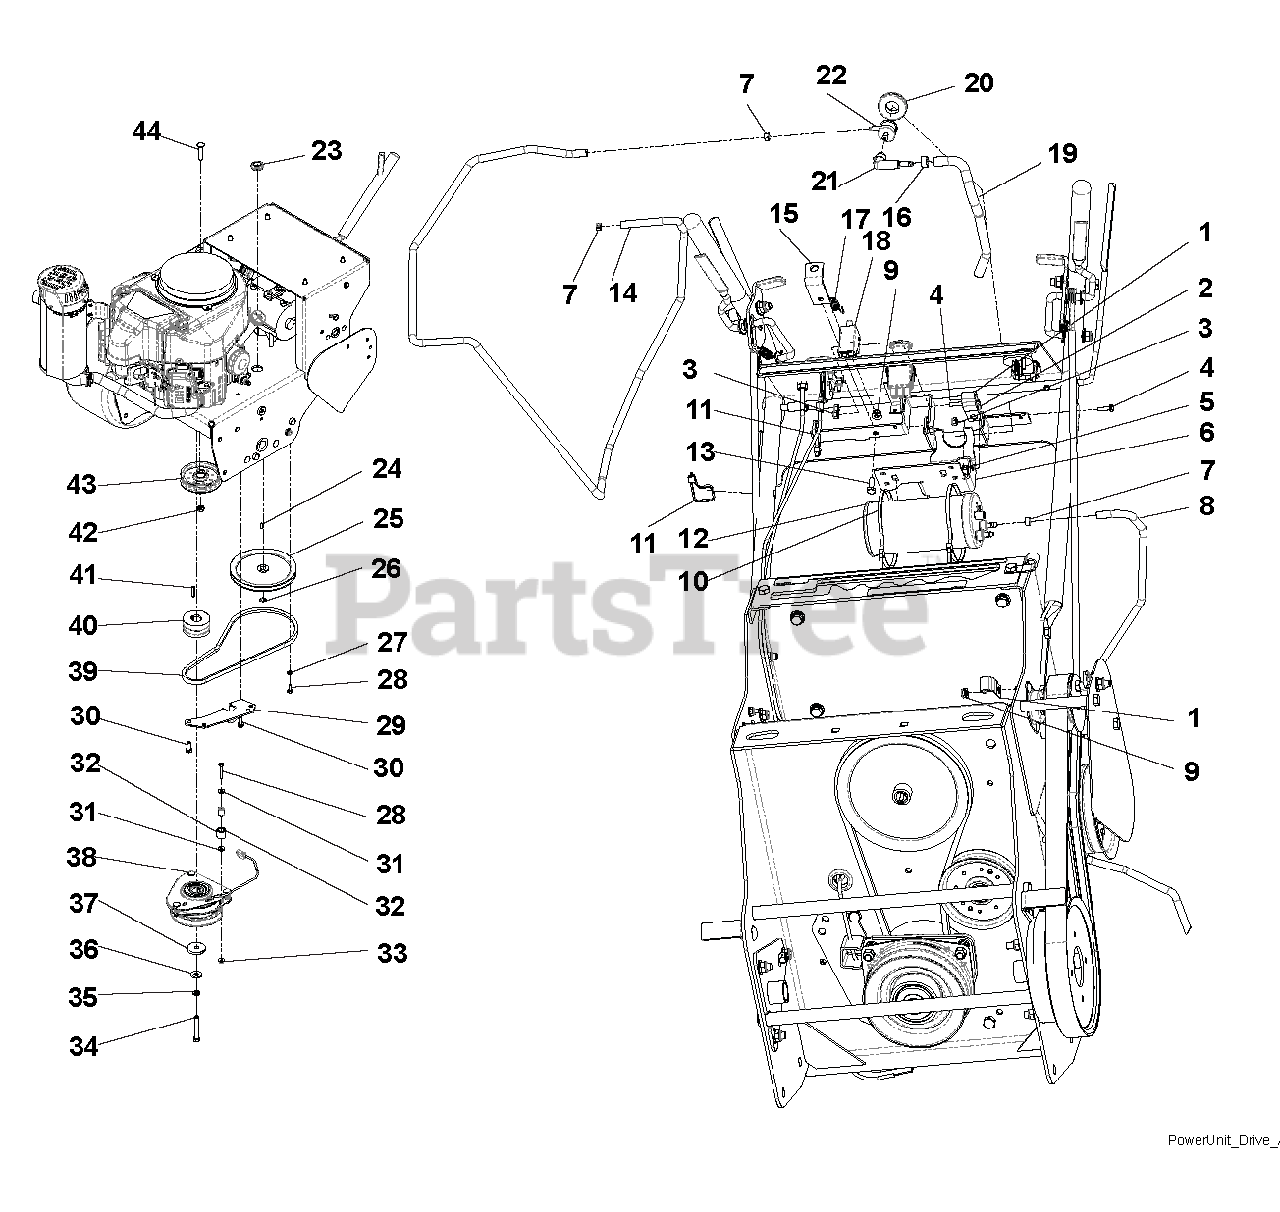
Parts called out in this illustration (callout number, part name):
1	P-CLIP, .500 INSULATED
2	NUT-LK-FLG M8-1.25 YWZC
3	@NUT-LK-NYL 10-24 W/INSRT YWZC
4	@SCR-MCH 10-24X.75 HWH YWZC
5	@BLT-HEX M8 X 1.25X14 YWZC
6	BRACKET, ROV & CC GEAR WALK
7	CLAMP, DBL PINCH 5/16"-7/16"
8	HOSE, PURGE LINE 3/16 GRWLK
9	@NUT-LK-NYL-FLG .25-20 YWZC
10	CABLE TIE, .19 X 14.4
11	CABLE TIE, .15 X 8.50
12	400 CC CARBON CANISTER 3/16 PT
13	@BLT-HEX .25-20X.75 GR5 YWZC
14	HOSE, 3/16 REMOTE ROV-CANISTER
15	BRACKET, BRAKE LINK
16	CLAMP, FUEL LINE
17	SPRING-EXT .047X.438X1.45
18	SWITCH,INTERLOCK
19	HOSE, 1/4" TANK-REMOTE ROV GRW
20	GROMMET, REMOTE ROV
21	ELBOW FITTING, 1/4 X 1/4 ASSY
22	VALVE, REMOTE ROLL OVER
23	GROMMET:RUB:.88IDX1.38ODX.14GR
24	KEY-WDRF .19X.75 HRD #9
25	PLY-V 7.50 X .626
26	RG-RTNG-EXT .579X.035
27	@WSHR-LK .31X.078 REG YWZC
28	@BLT-HEX .31-18X.75 GR5 YWZC
29	WLDT, CLUTCH STOP G2
30	BLT-HEX .38-16X1.0 GR8 YZ EP30
31	@WSHR-FL-STL.312X.734X.065 YWZ
32	BUMPER,RUBBER .62X1.0X.88 LG
33	@NUT-LK-NYL-FLG .31-18 YWZC
34	BLT-HEX .44-20X3.00 G5 YZ EP80
35	@WSHR-LK .44X.109 REG YWZC
36	@WSHR-FL-STL.50X1.25X.083 YWZC
37	WSHR-FL-STL .469X2.00X.25 YWZC
38	CLUTCH ASSY, OGURA# GT1A-HU02
39	V-BELT, HA-RAW EDGE
40	SHEAVE,ENGINE 1.002IDX3.222PIN
41	KEY-SQ .248X1.25X.248
42	@NUT-LK-NYL-FLG .38-16 YWZC
43	ASM, IDLER 4"
44	BLT-RDHDSQNK .38-16X2.00 SHTYW
